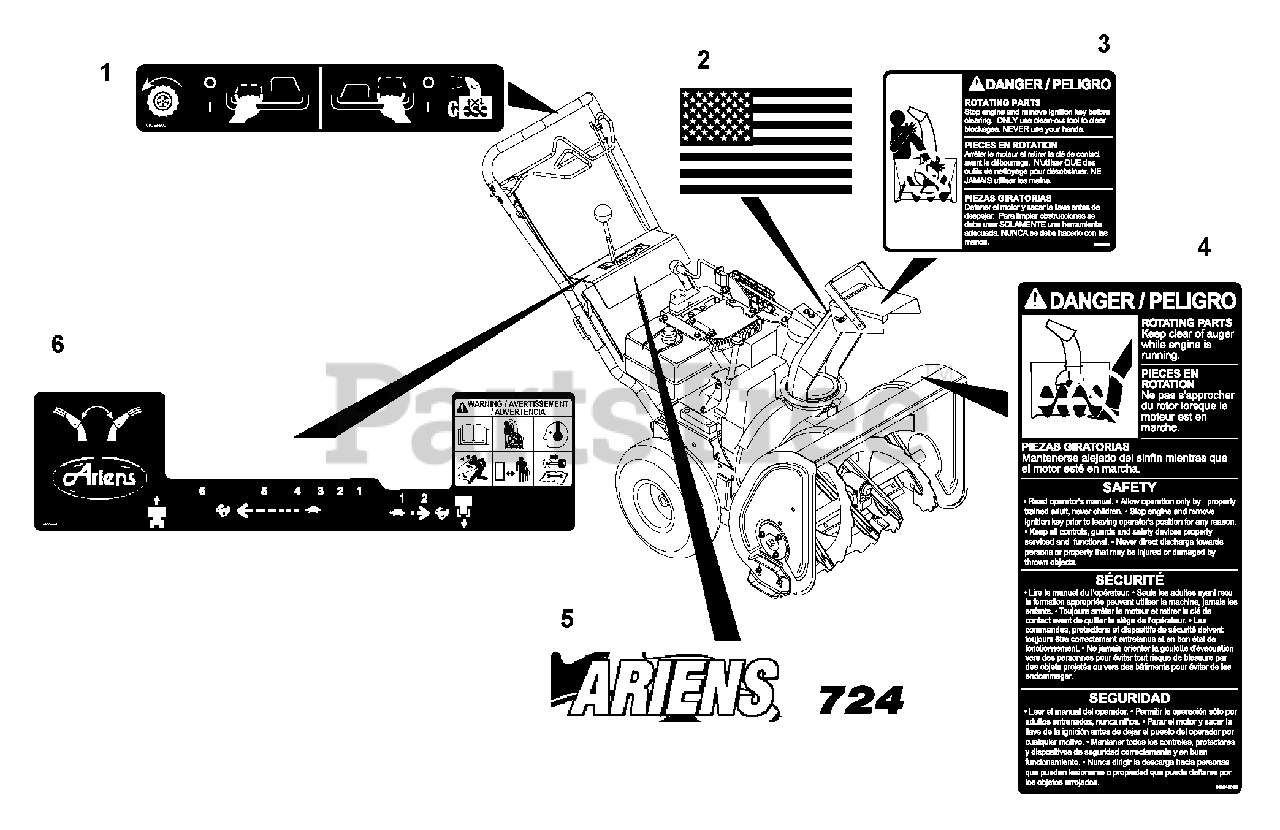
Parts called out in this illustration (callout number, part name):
1	DECAL, BAIL
2	DECAL, AMERICAN FLAG
3	DECAL, DANGER - ROT. PARTS
4	DECAL, DANGER
5	DECAL, FRONT PANEL, ST520
6	DECAL, CONTROL PANEL, COMPACT
